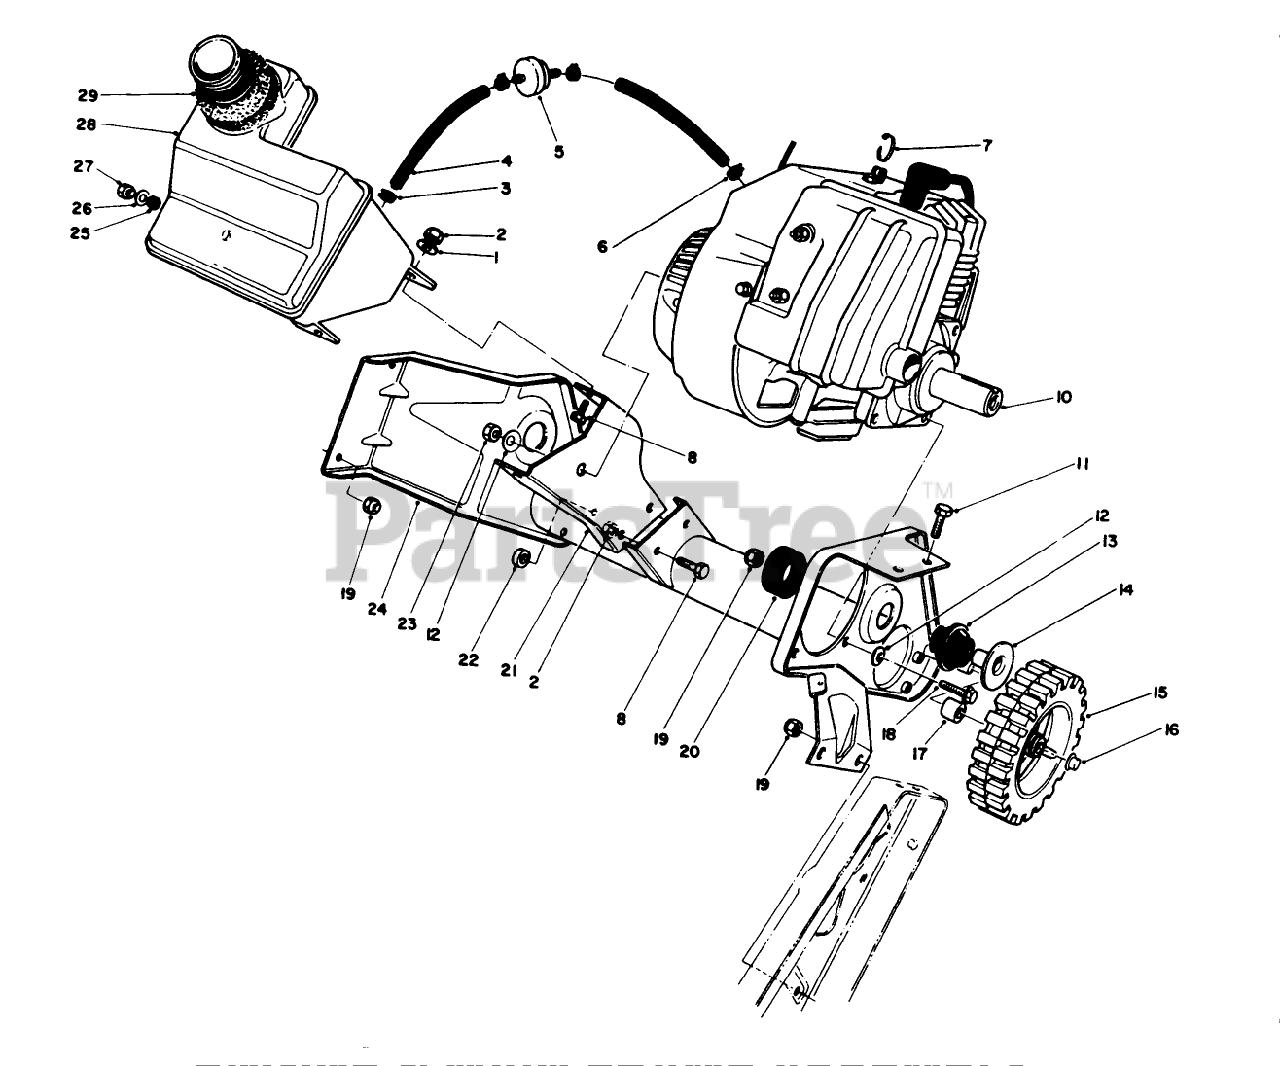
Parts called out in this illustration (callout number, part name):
1	WASHER-FLAT
2	NUT-LOCK, NI
3	Clamp
4	GAS LINE
5	FILTER-FUEL
6	CLAMP-HOSE
7	TIE-CABLE
8	SCREW-HH
10	Engine Assembly
11	SCREW-HH
12	WASHER-BELLEVILLE
13	MOUNT-REBOUND
14	SPACER TUBE
15	WHEEL
16	NUT-PUSH
17	SPACER-WHEEL
19	NUT-LOCK, NI
20	LOAD MOUNT
21	Support-Recoil
22	SPACER-WHEEL
23	NUT (F/W & PPP)
24	Wa-Frame
25	GROMMET-RUBBER
26	WASHER-PLAIN
27	NUT-LOCK, CONE
28	Tank-Fuel (Incl. Ref. #25)
29	SEAL-FOAM
